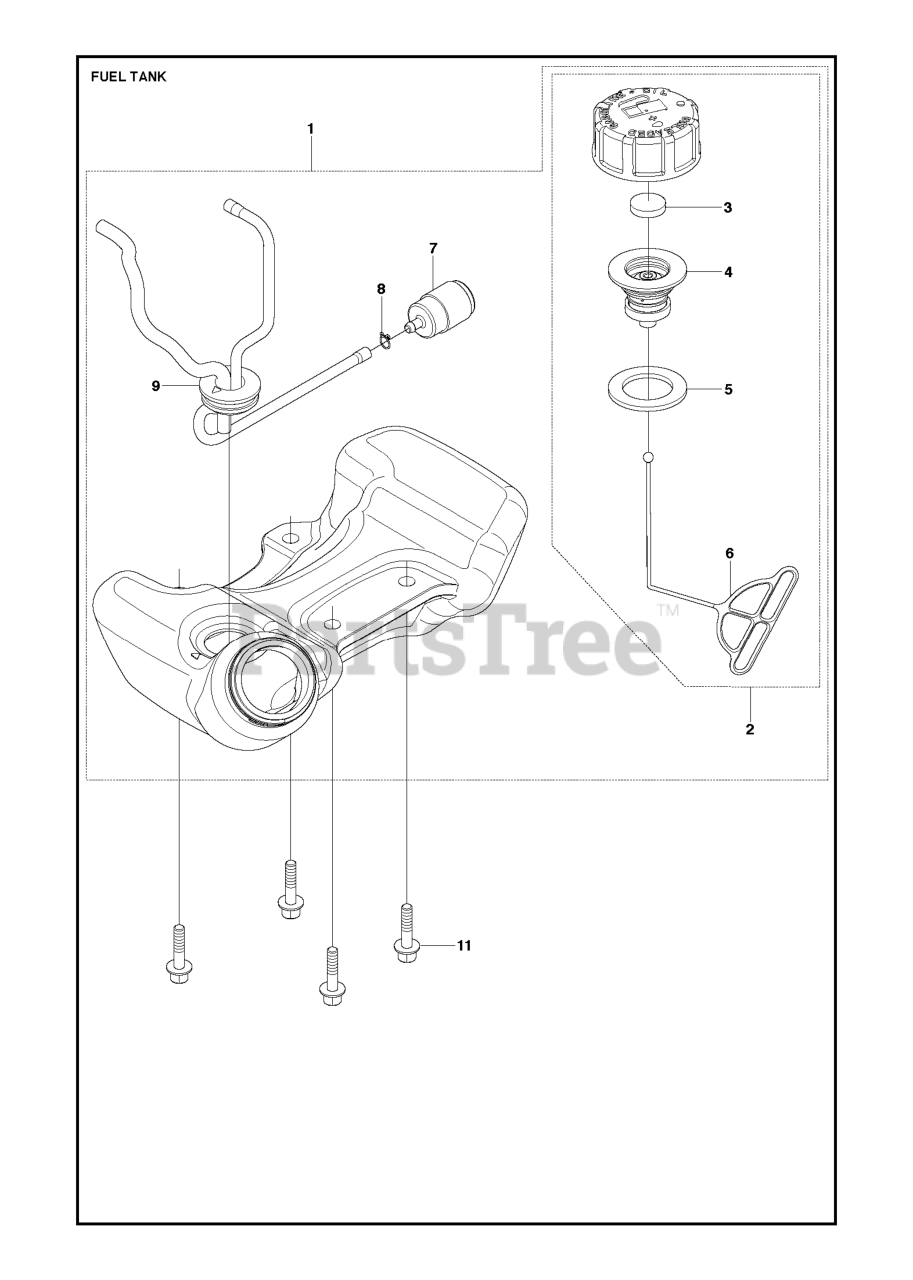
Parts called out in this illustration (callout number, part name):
1	NUT M53S / M48S
3	WHEEL PRO HUSQVARNA
4	BALL BEARING 6201-2RS/C3 W10
5	WHEEL ASSY PRO HUSQVARNA
6	SPACER PRO
7	LOCKING NUT FLANGE
8	SPACER M53 L=14
9	SPACER WASHER M53S / M48S
10	SHIELD PRO
13	RING M53S / M48S
14	RETAINING RING
17	SPRING M53 / M48
18	BALL M53 / M48
21	LEVER ASSY M53 / M48 M53
23	SPRING M53 / M48
24	FLANGE NUT
25	BOLT FLANGE M6X16
28	AXLE ASSY M53 PRO
29	CHASSIS M53S HUSQVARNA WITH CR
33	SPRING M53 / M48
35	PINION PRO
44	SCREW RXS B8X9.5
46	BRACKET M53 / M48
47	SPRING M53S / M48S
48	SCREW ITXPANTT M5X10 ZPB (A00
49	CUP PRO
52	WHEEL PRO, DRIVING HUSQVARNA
53	WHEEL ASSY PRO, DRIVING HUSQVA
